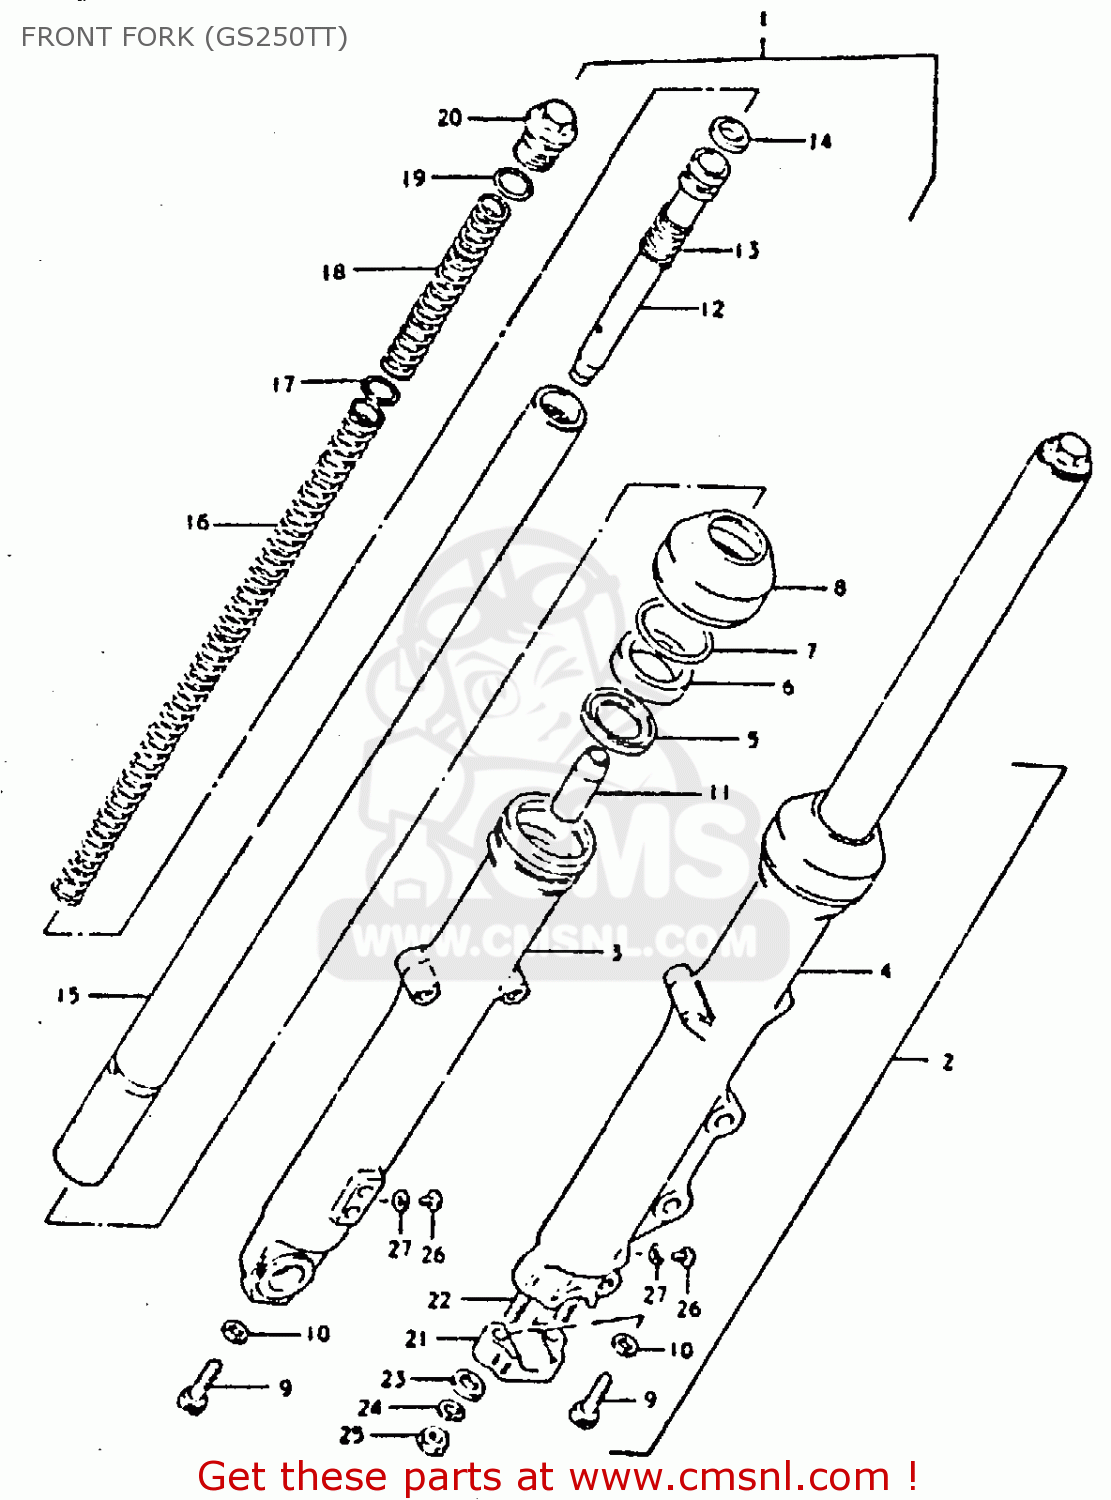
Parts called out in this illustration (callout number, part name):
1	DAMPER ASSEMBLY,FRONT FORK
2	DAMPER ASSEMBLY,LEFT
3	TUBE,FORK,OUTER,RIGHT
4	TUBE,FORK,LEFT,OUTER
5	SPACER,OIL SEAL
6	OIL SEAL,FRONT FORK
7	CIRCLIP,FORK OIL SEAL
8	BOOT
9	BOLT(8X27)
10	GASKET (NAS)
11	PIECE,OIL LOCK
12	CYLINDER,FRONT FORK
13	SPRING,REBOUND
14	RING,PISTON
15	TUBE,INNER
16	SPRING
17	SEAT,SPRING
18	SPRING,FRONT FORK
19	O RING
20	BOLT
21	HOLDER,AXLE
22	STUD 8X25
23	WASHER
24	LOCK WASHER
25	NUT (8MM)
26	SCREW 4X6
27	GASKET (NAS)
